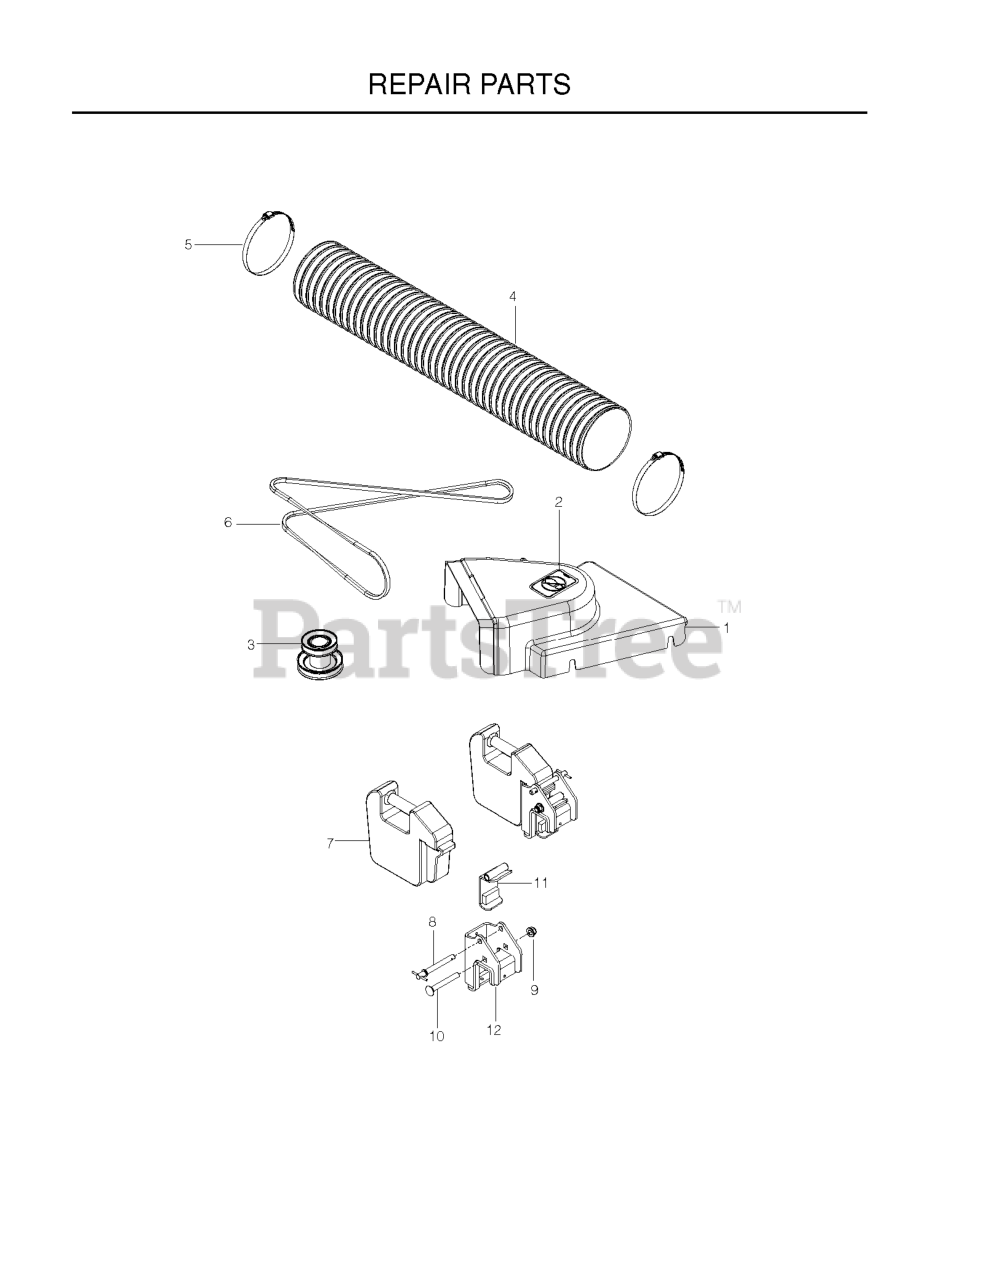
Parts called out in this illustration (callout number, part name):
1	SHIELD, BELT, 48"
2	DECAL, NO STEP
3	PULLEY, 48" STACK
4	HOSE, 7" X 42"
5	CLAMP, HOSE
6	BELT, 48/52"
7	FRONT WEIGHT CAST PZ DFS
8	PIN, DETENT
9	NUT, 1/2-13 HEX FLG NYLOC ZD
10	RHSNB 1/2-13 X 4 GR 5 ZD
11	LATCH, WELDMENT
12	BRACKET, WEIGHT, BLK
